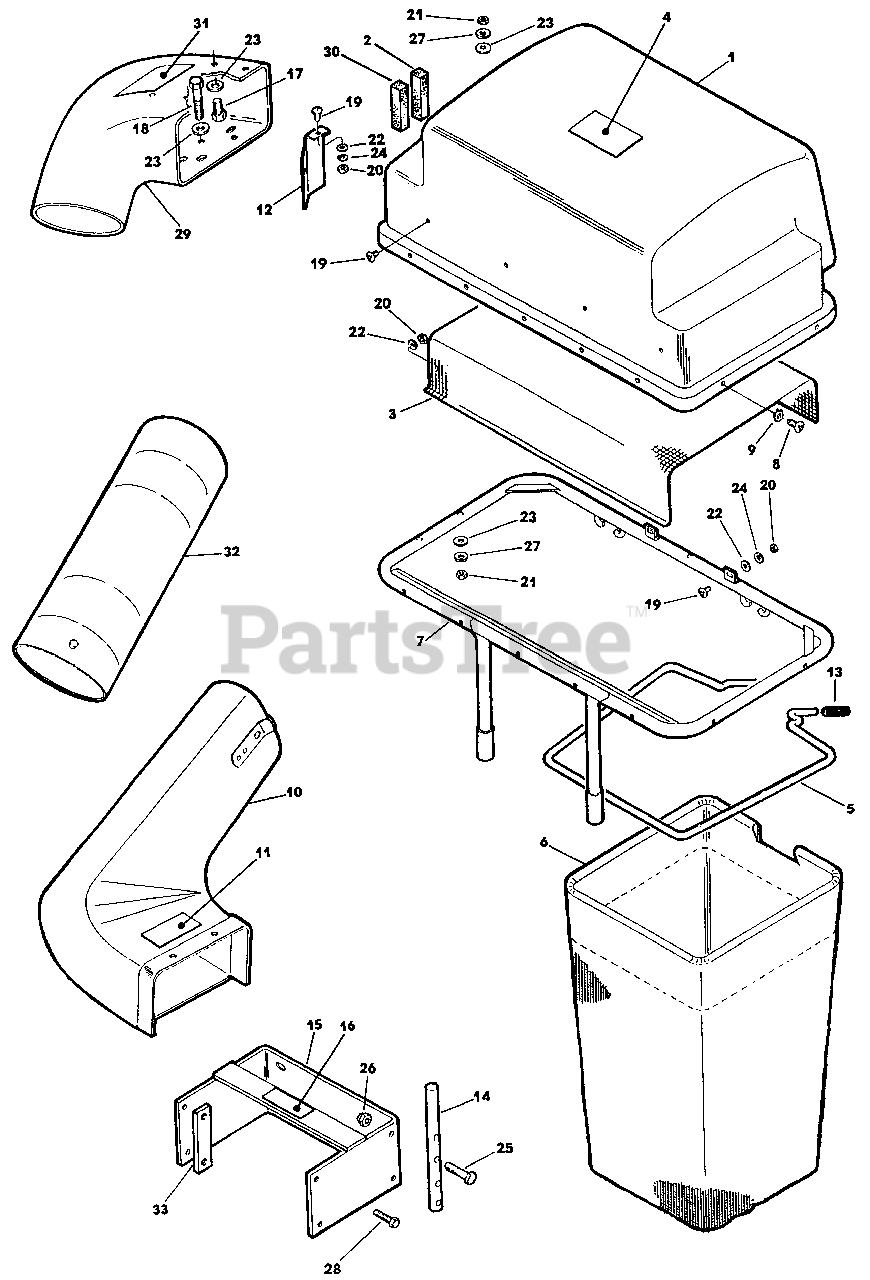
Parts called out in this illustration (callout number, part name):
1	Cover Ass'y. w/Decal (Includes Cover, Decal, Screen And One Foam Pad)
2	Foam Pad
3	Screen
4	Decal-Warning
5	Grass Bag Frame
6	Grass Bag
7	Hanger Assembly
8	Screw, Self Tapping
9	Lock Washer, External Tooth
10	Adaptor Assembly w/Decal
11	Decal-Danger
12	Shield
13	Grip
14	Mounting Bar
15	Mounting Bracket w/Decal
16	Decal-Warning
17	Cap Screw, Hex Hd
18	Cap Screw, Hex Hd
19	Machine Screw, #10-24 x 5/8"
20	Nut, #10-24 Hex
21	Nut, Hex
22	Washer, Flat
23	Washer, Flat
24	Washer, Spring Lock
25	Cap Screw, Hex Hd
26	Nut, Hex Cone Lock
27	Washer, Lock
28	Screw
29	Chute Extension w/Decal
30	Foam Pad
31	Decal-Danger
32	Tube
33	Spacer
